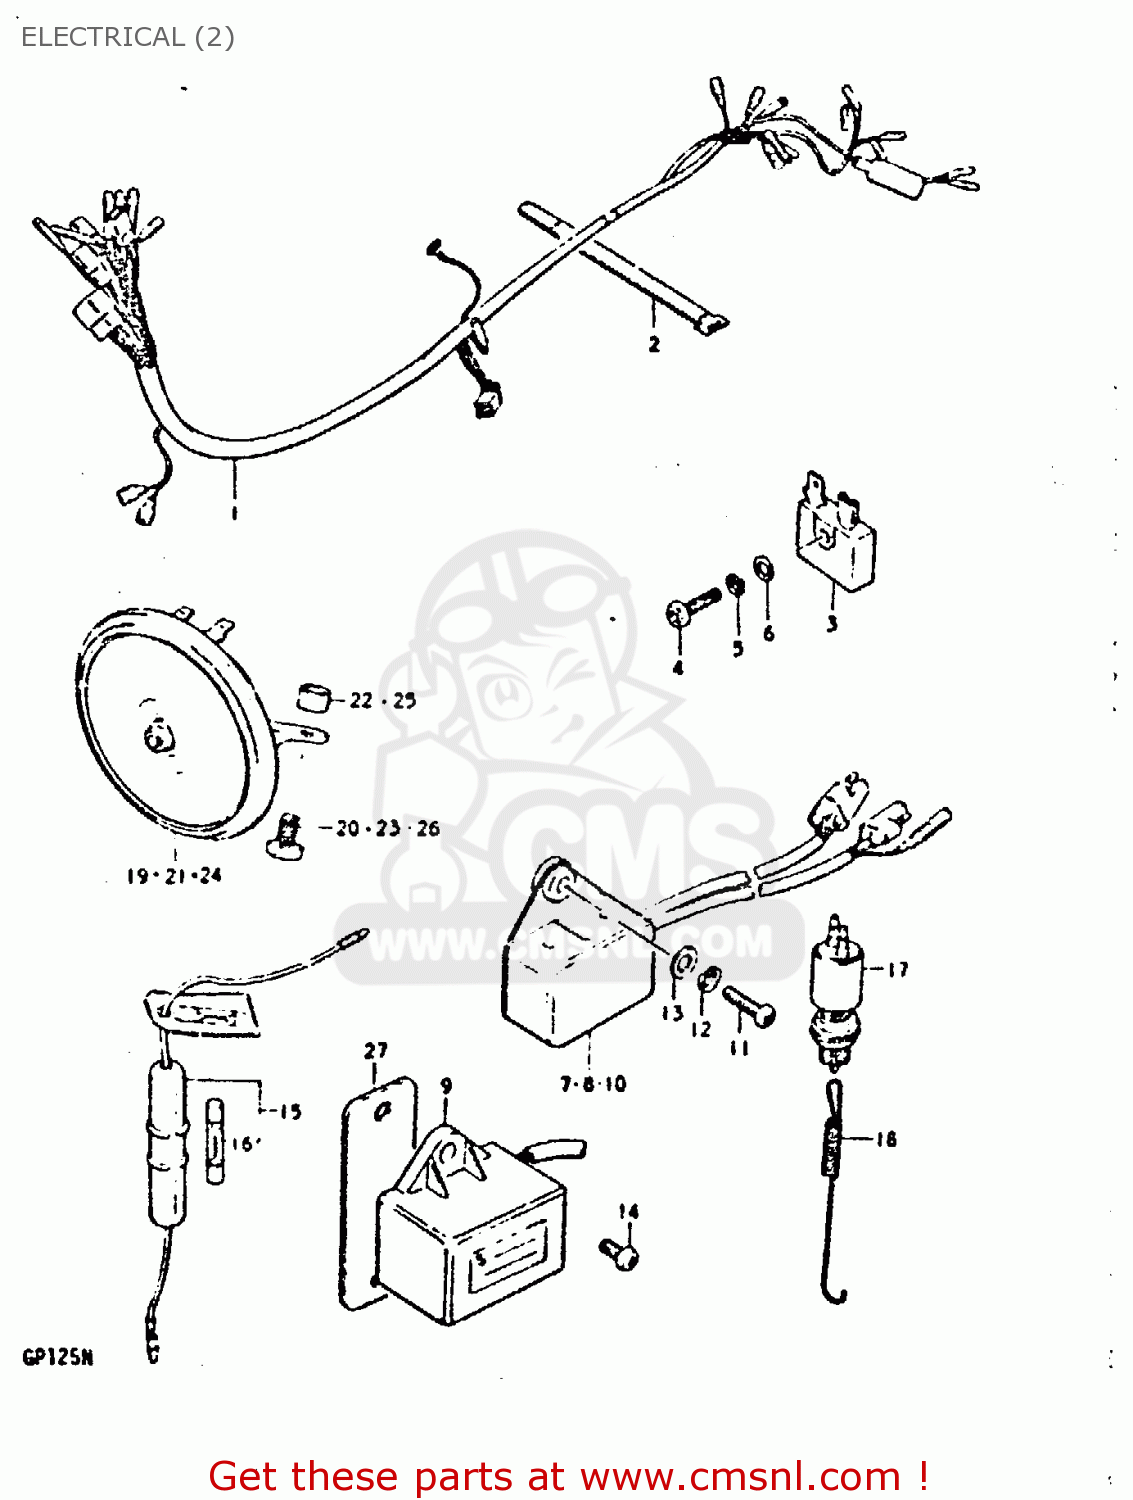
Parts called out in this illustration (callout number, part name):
1	WIRING HARNESS
2	CLAMP
3	RECTIFIER ASSEMBLY
4	SCREW 5X20
5	LOCK WASHER
6	WASHER
15	BOX ASSEMBLY,FUSE
16	FUSE(10A)
17	SWITCH ASSY,BRAKE LAMP
18	SPRING
19	HORN ASSY
20	BOLT
